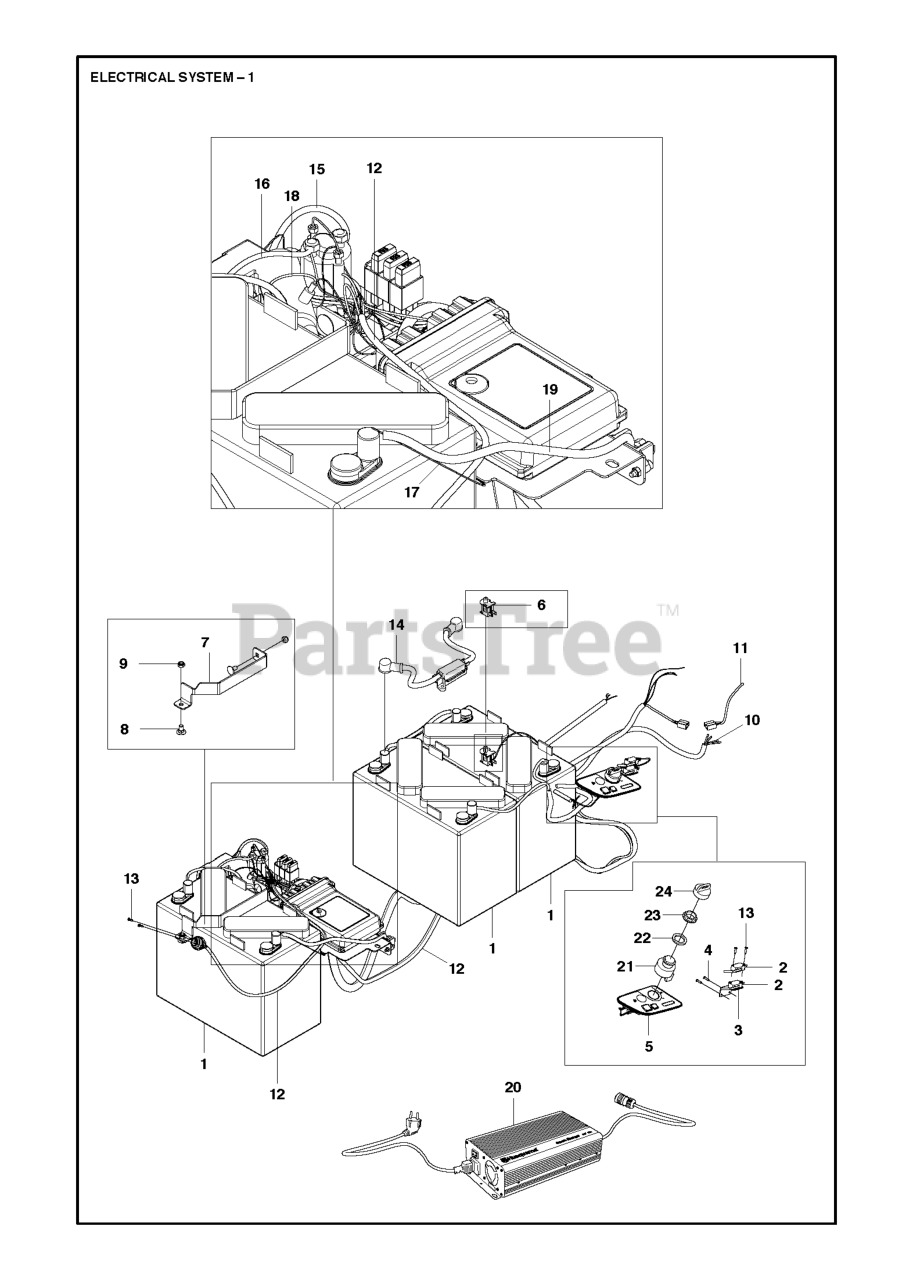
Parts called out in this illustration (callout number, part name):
2	MICRO SWITCH
6	SEAT SWITCH
9	LOCKNUT M8
